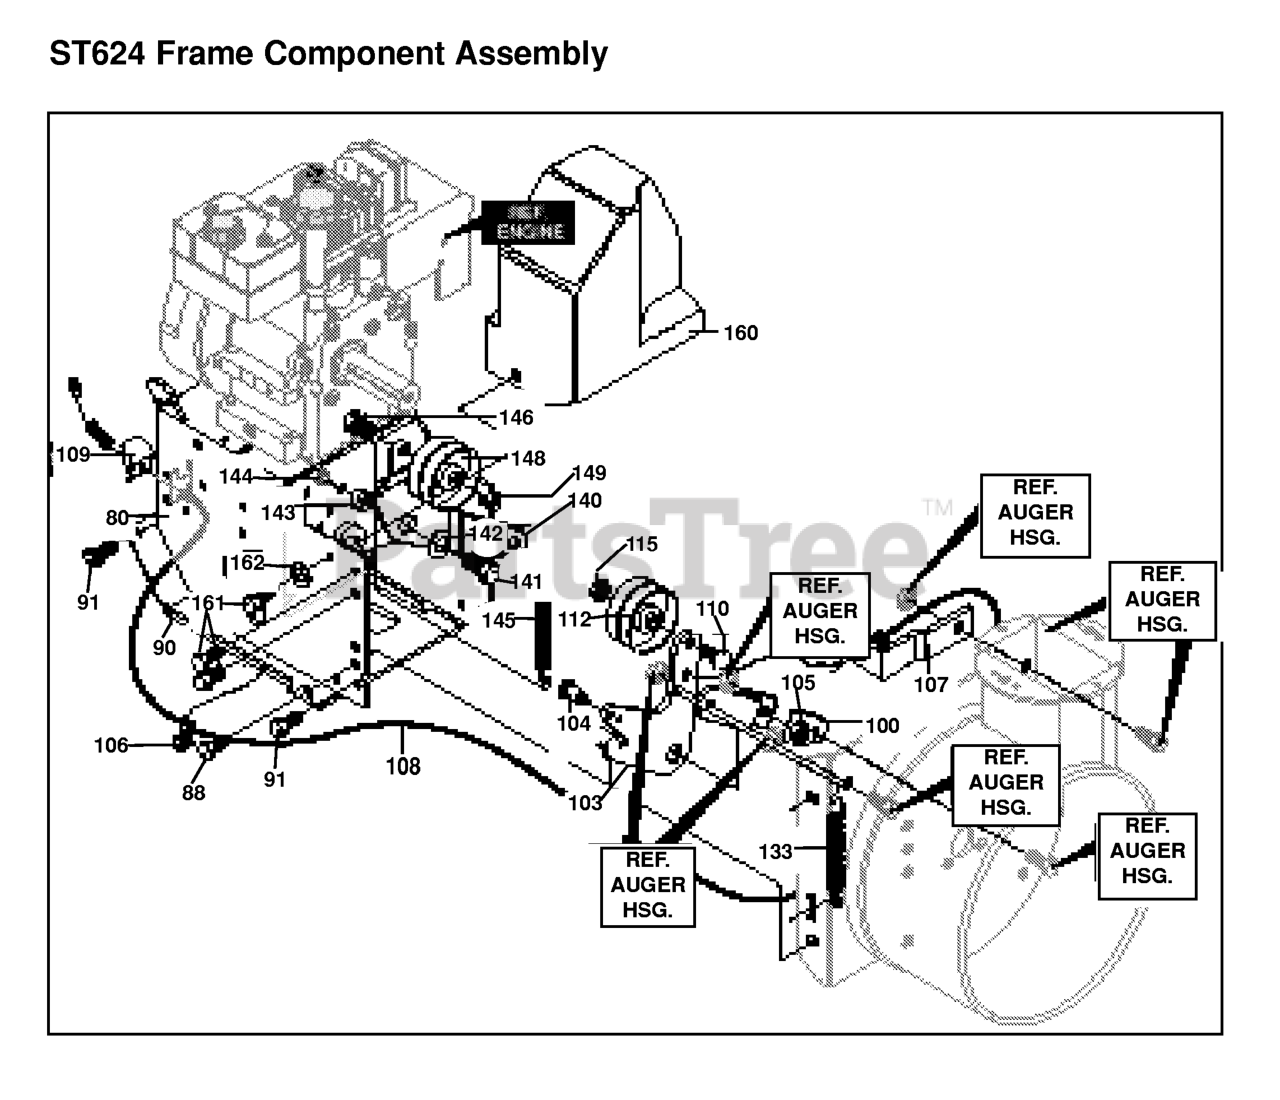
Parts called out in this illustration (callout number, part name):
80	FRAME, ASSY
88	SCREW, 5/16-18X .50 WAHHT
100	PLATE, CLU. ARM MT
103	ARM-CLUTCH CABLE
104	Bolt, .497 x .138 3/8-16
106	CLIP, CABLE TINN
107	Bracket, Compact Cable
108	CABLE
109	SHIELD, CABLE GROUND
110	SCREW, 3/8-16 X 1.25
112	IDLER PULLEY
141	SCREW, 5/16-18X .75 HHC
146	SCREW, 3/8-16 X 1.25
148	IDLER PULLEY
160	COVER, BELT
162	WASHER, FLAT .281X .63X.
